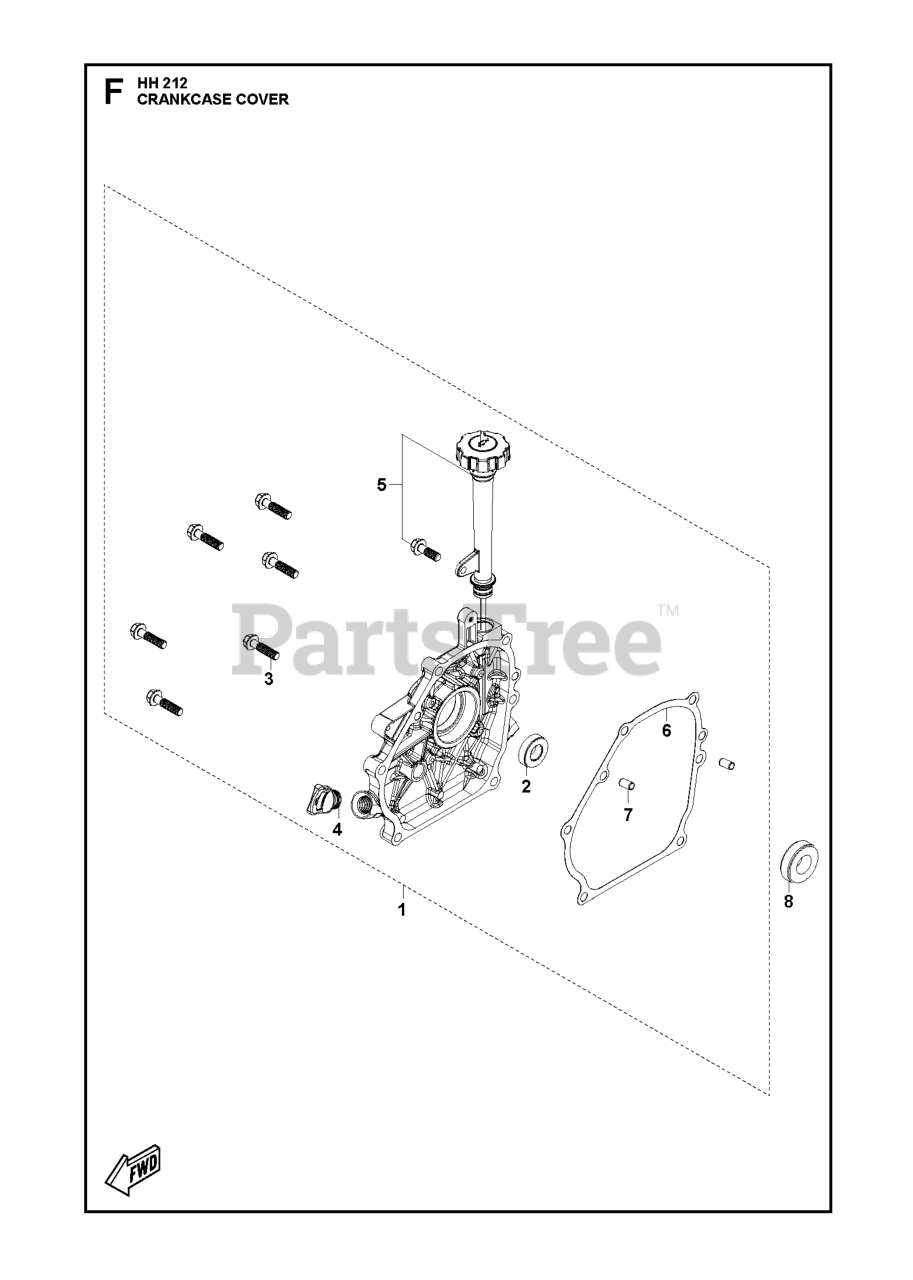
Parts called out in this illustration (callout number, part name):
1	CRANKCASE ASSY CRANKCASE COVER
2	SEAL OIL SEAL
3	BOLTS
5	DIPSTICK DIPSTICK KIT
6	GASKET CRANKCASE COVER GASKET
7	PIN LOCATION PIN
8	BALL BEARING
